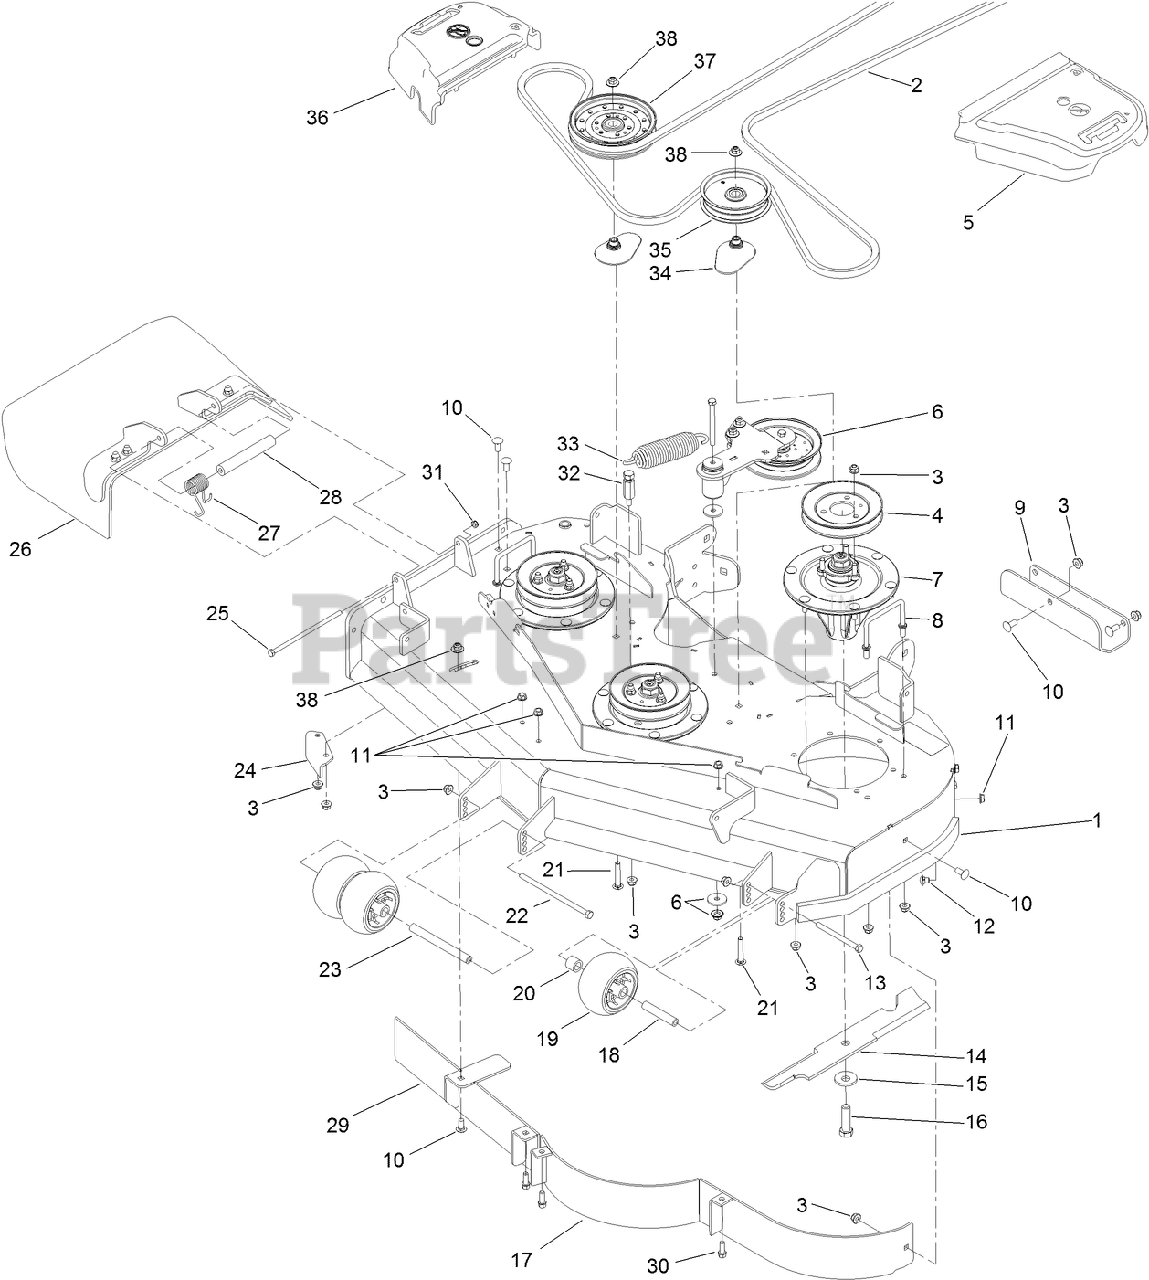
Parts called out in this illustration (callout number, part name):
1	DECK DECAL ASM
2	BELT-V
3	NUT-HF, NI
4	PULLEY
5	COVER-BELT, LH
6	IDLER ARM ASM
7	SPINDLE ASM
8	WIREFORM-COVER
9	PLATE-SKID
10	SCREW-CARR
11	NUT-HHF, WHIZ
12	SCREW-CARR
13	SCREW-HH
14	BLADE-16.5 INCH (HIGH FLOW)
15	Washer-Blade Bolt, Heavy
16	SCREW-BLADE
18	TUBE-SPANNER
19	ROLLER-SCALP, ANTI
20	TUBE-SPACER
21	BOLT-CARR, SHORT NECK
22	SCREW-HH
23	SPACER-WHEEL
24	BAFFLE-DISCHARGE
25	SCREW-HH
26	RUBBER DEFLECTOR ASM
27	SPRING-TORSION
28	SPACER
29	BAFFLE ASM
30	SCREW-HWH
31	NUT-LOCK, NI
32	ANCHOR-SPRING, TALL
33	SPRING-EXTENSION
34	SPACER-PULLEY
35	PULLEY-IDLER, FLAT
36	COVER-BELT, RH
37	PULLEY-IDLER, FLAT
38	NUT-FLANGE, NI
